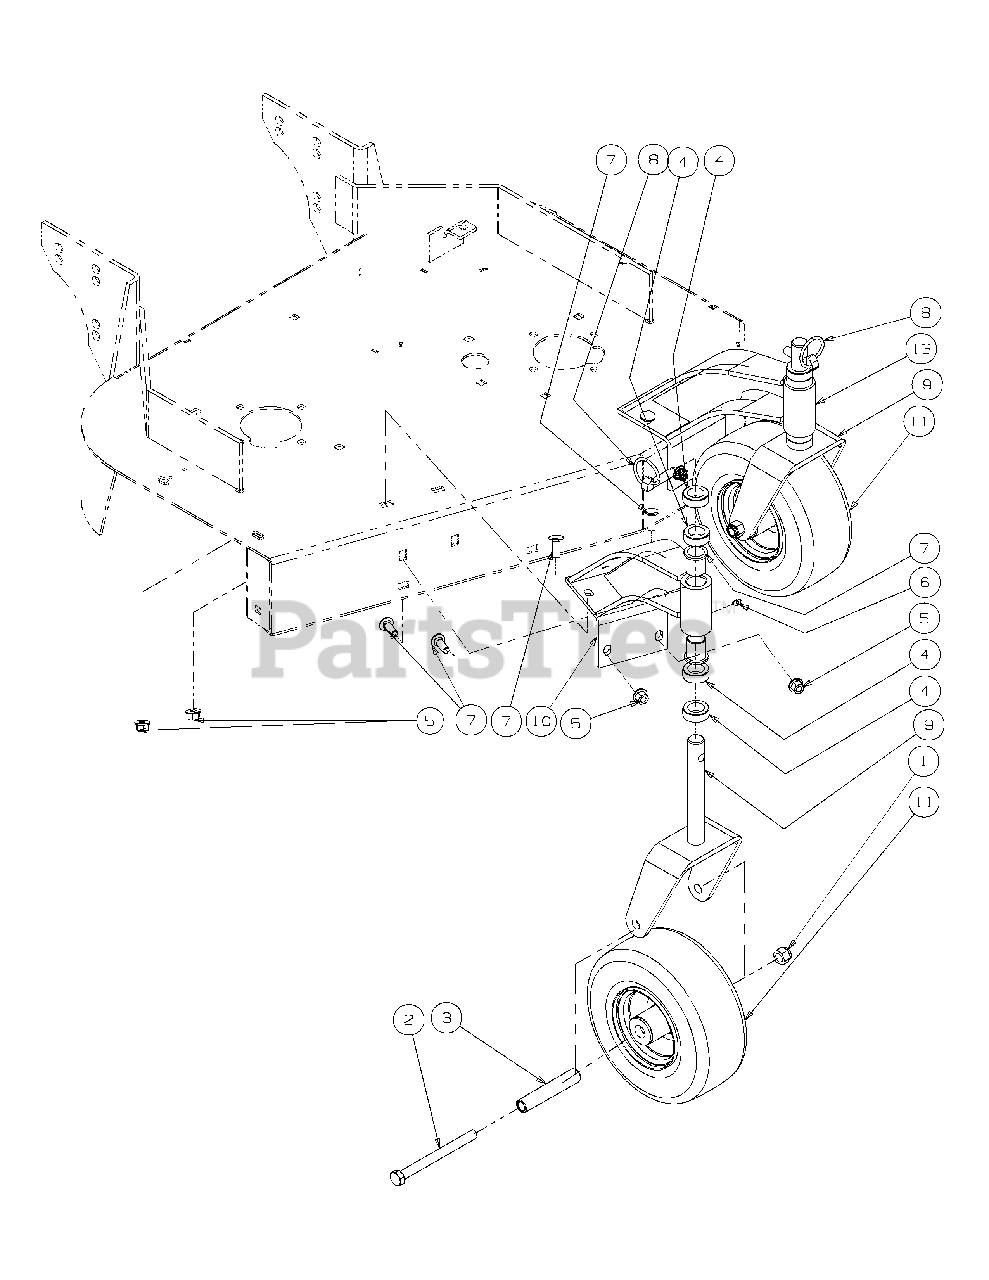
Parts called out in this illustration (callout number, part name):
1	Lock Nut, Nylon Insert, 1/2-13
2	Hex Cap Screw, 1/2-20, 5.50
3	Spacer Wheel
4	Spacer, Caster
5	Hex Nut Flange Lock, 3/8-16
6	Grease Fitting, 1/4-28 x 3/16
7	Carriage Bolt, 3/8-16 x 1
8	Klik Pin, 1.75
10	Caster Bracket Assembly
11	Wheel Assembly, 9.0 x 3.50-4
